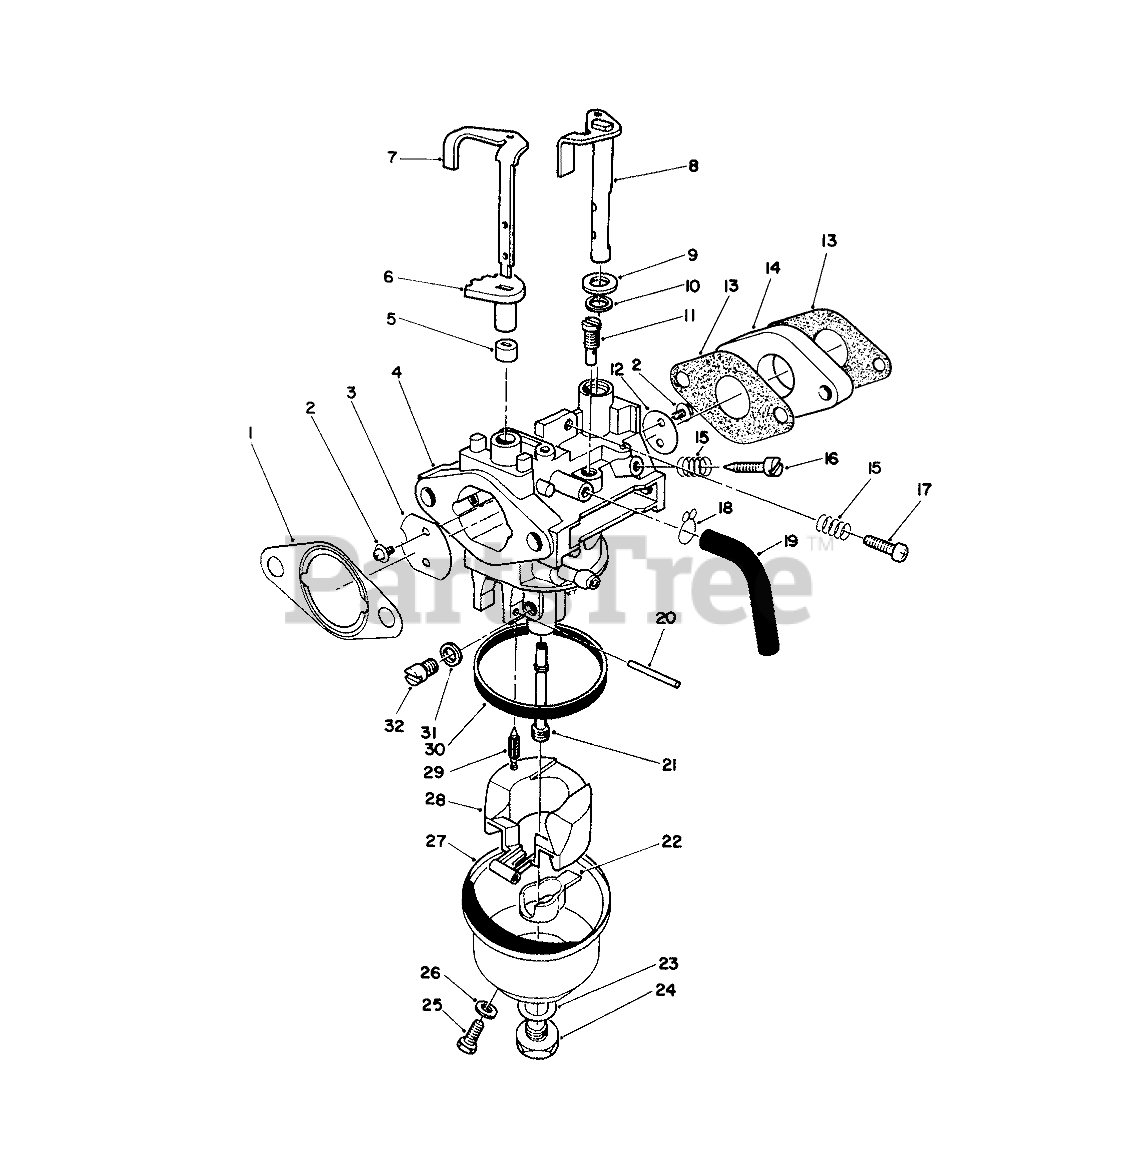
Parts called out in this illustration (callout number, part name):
1	GASKET F/W ENGINE
2	Screw
3	VALVE
4	Body-Carburetor
5	LOWER CHOKE RING
6	UPPER CHOKE RING
7	Shaft-Choke Valve
8	SHAFT
9	WASHER
10	Seal-Throttle Shaft
11	JET - PILOT
12	VALVE
13	GASKET INTAKE
14	INSULATOR - CARB.
15	SPRING-PILOT SCREW
16	ADJUSTER
17	SCREW
18	CLAMP
20	Pin
21	NOZZLE - MAIN
22	SPACER
23	GASKET
24	SCREW
25	SCREW
26	GASKET
28	FLOAT
29	NEEDLE
30	FLOAT BOWL GASKET
31	SPACER
32	JET-HIGH ALTITUDE
